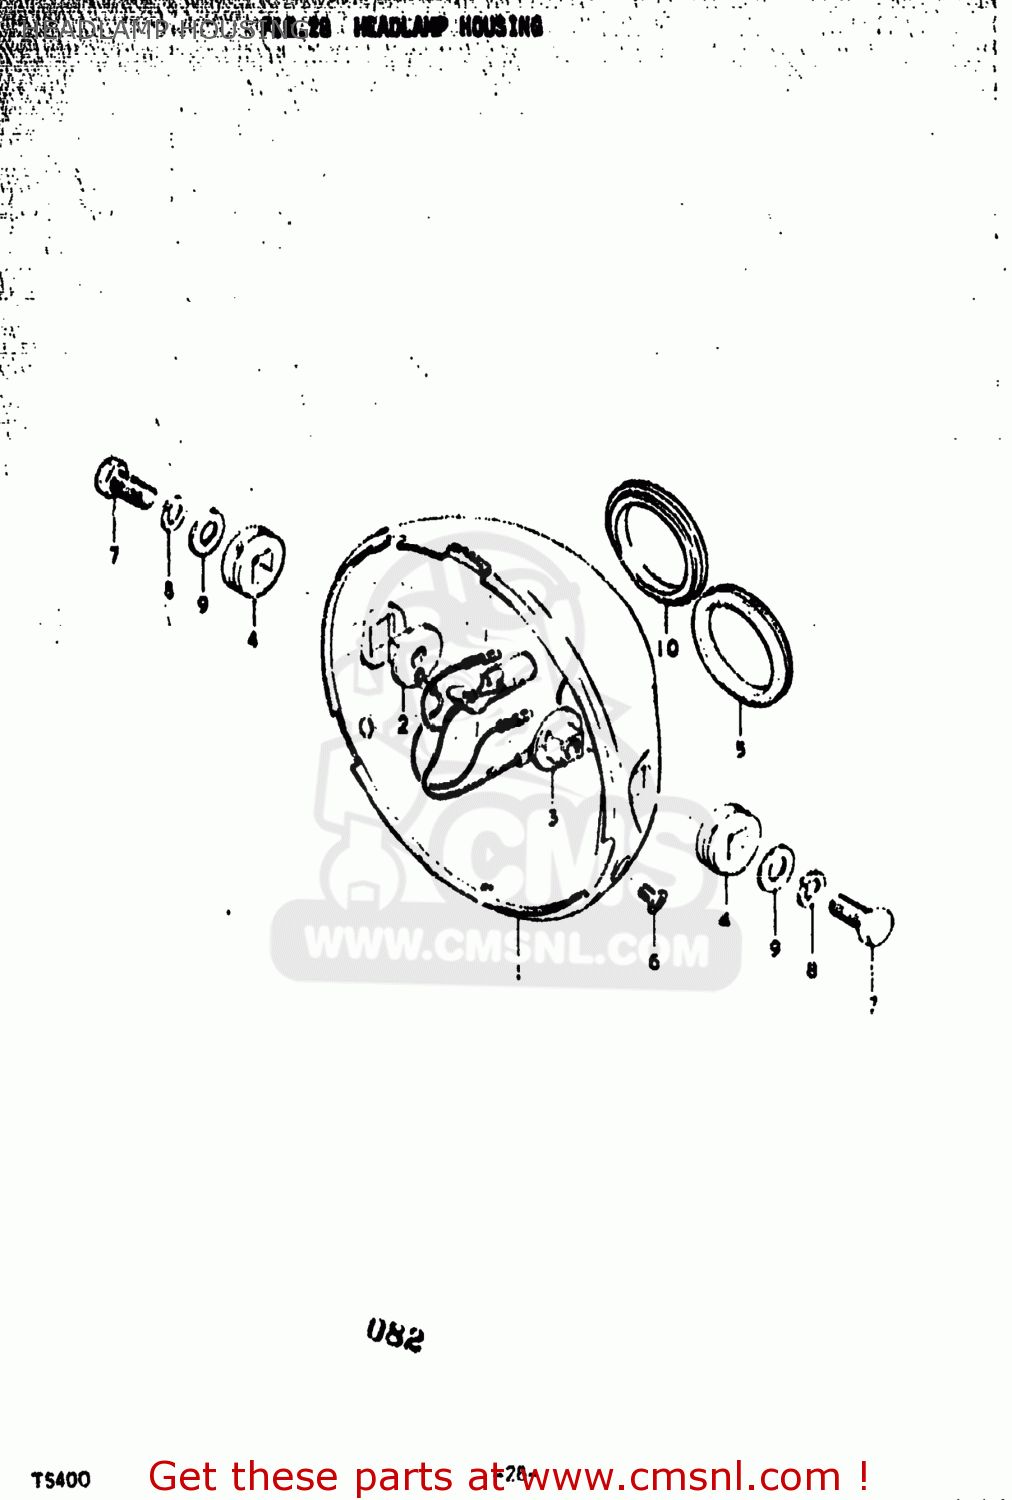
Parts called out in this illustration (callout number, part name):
1	HOUSING COMP,HEADLAMP
2	SPACER, HOUSING RH
3	SPACER, HOUSING LH
4	CUSHION,HEADLAMP HOUSING
5	GROMMET,HEADLAMP HOUSING
6	SCREW(5X12)
7	BOLT
8	LOCK WASHER
9	WASHER
10	CAP
